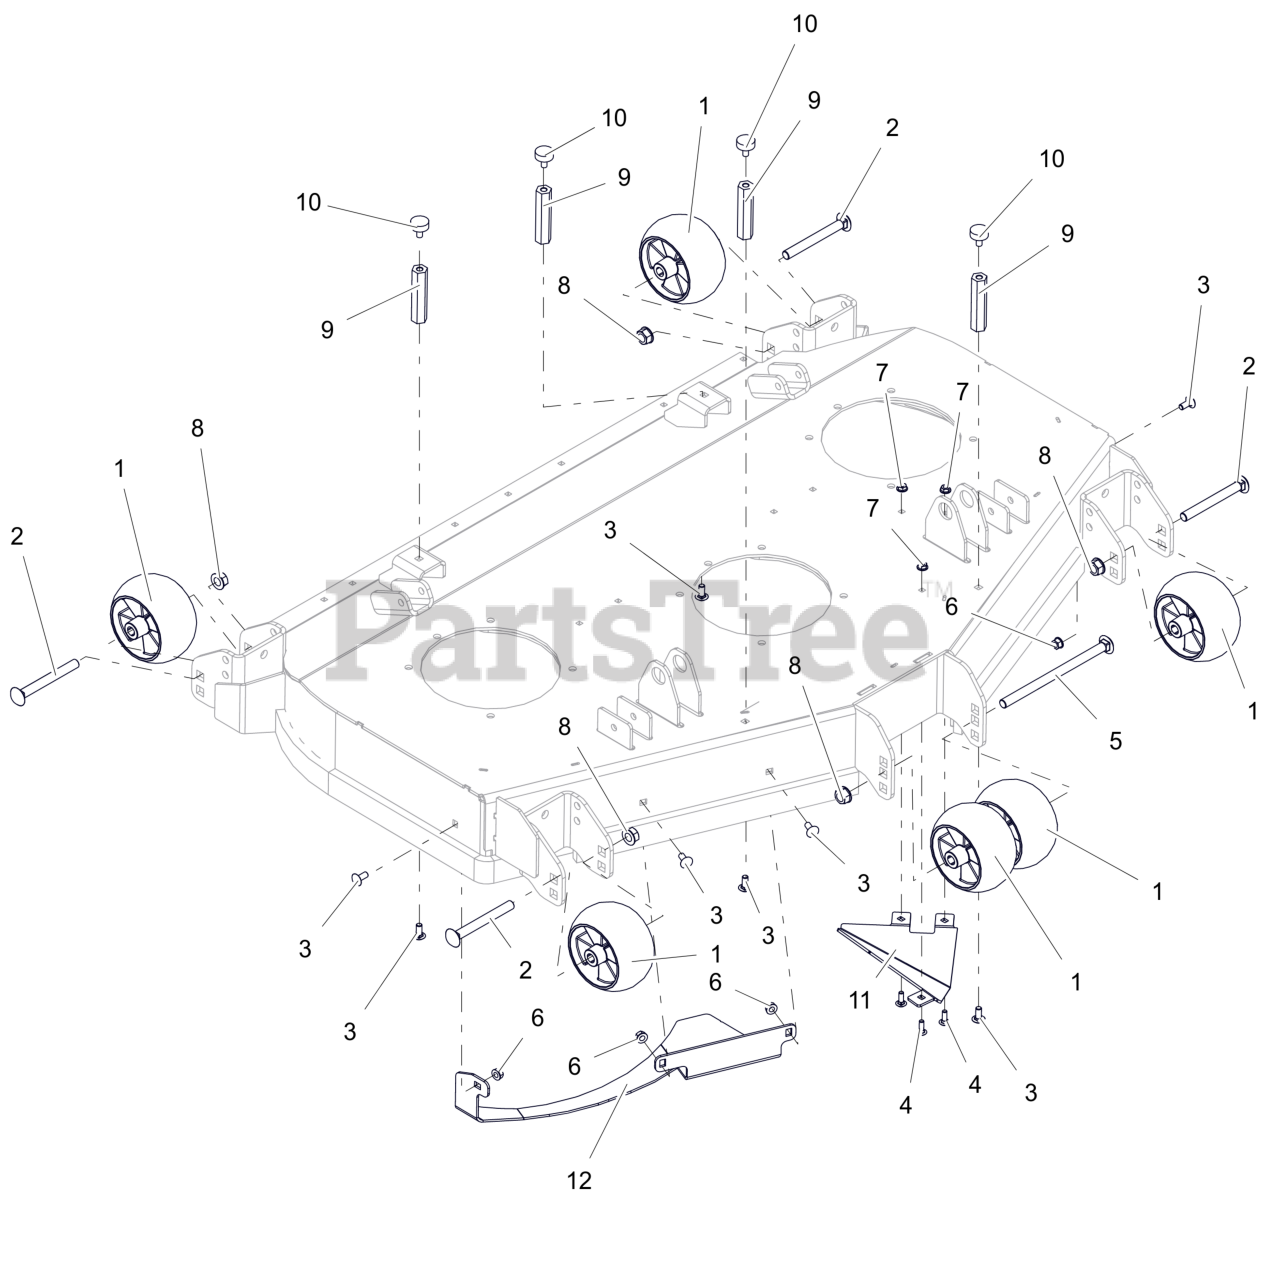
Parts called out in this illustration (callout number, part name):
1	WHEEL, ANTI SCALP - 5X3 CTR W/RIBS
2	BLT,RHSN .50-13X4.50 G5 ZCC
3	BLT, RHSSN.31-18X.750 G5 ZCC
4	BLT, RHSN .25-20X.750 G5 ZCC
5	BTL,RHSN .500-13 X 8 G5 ZCC
6	NUT,LK-CTR-FLG .31-18 GF ZCC
7	NUT-LK-CTR-FLG .25-20 ZC120
8	NUT-LK-CTR-FLG .500-13 GG ZCC
9	NUT, COUPLING .312-18 X 3.375
10	BUMPER, RUBBER
11	BAFFLE, 48" TRIANGLULAR INSERT (RED)
12	DEFLECTOR, BAFFLE BOLT-IN (RED)
